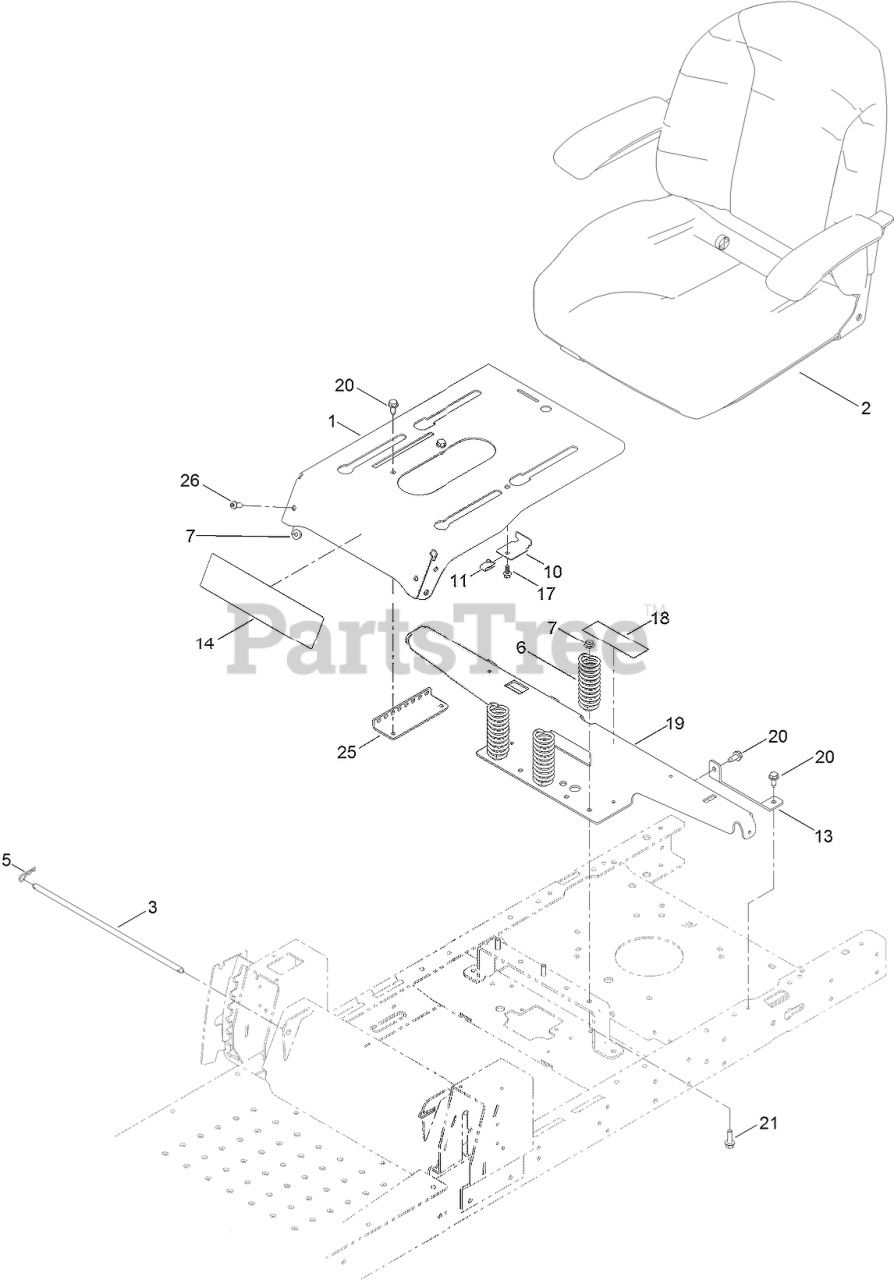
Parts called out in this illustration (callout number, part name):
1	PAN-SEAT
2	SEAT ASM
3	ROD-PIVOT, NARROW
5	PIN-COTTER
6	SPRING-COMPRESSION
7	NUT-HF, NI
10	BRACKET-STOP, SEAT
13	SUPPORT-TANK, REAR
14	DECAL-TIMECUTTER
17	SCREW-HHF
18	DECAL-SERVICE, CE
19	SUPPORT-POD
20	SCREW-HWHTF
21	SCREW-HHF
25	BRACKET-LATCH, SEAT
26	SCREW-HSBH
